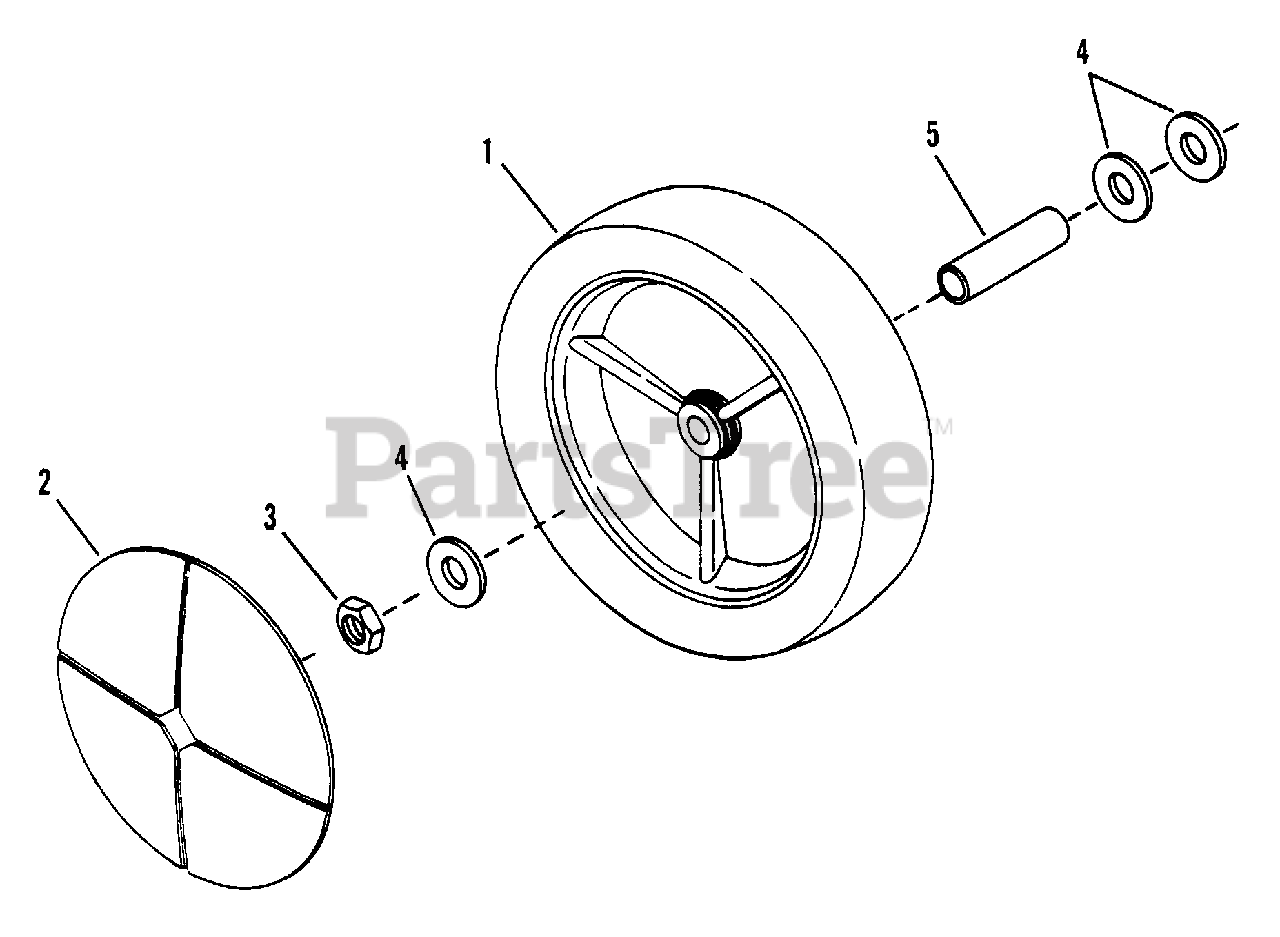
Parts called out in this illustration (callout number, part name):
1	WHEEL, 7 x 1.75 Plastic Rim
2	COVER, Wheel
3	NUT, 7/16-20 Hex Center Lock
4	WASHER, 7/16 Flat
5	BUSHING, Axle
